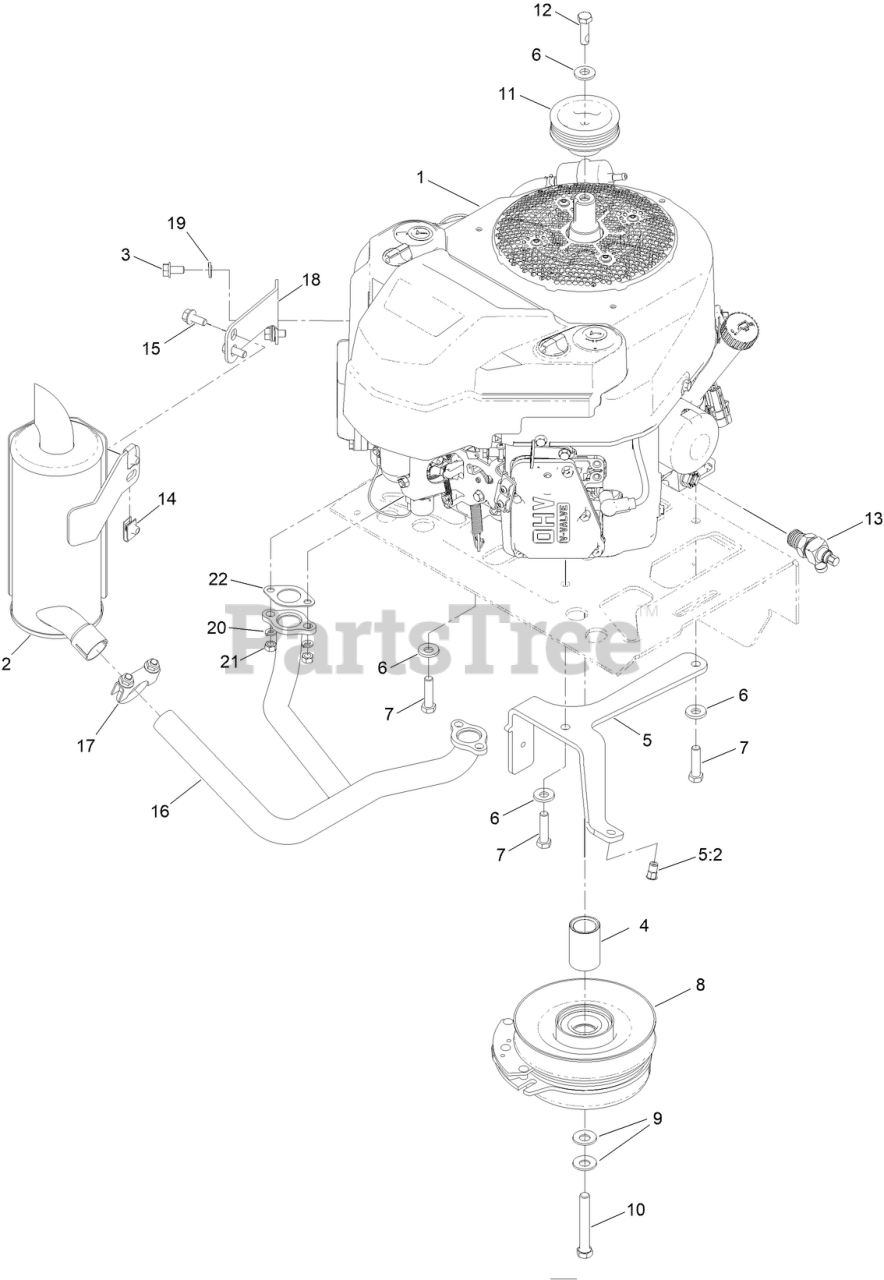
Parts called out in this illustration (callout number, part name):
1:1	KAWASAKI 49065-7007 ENGINE OIL FILTER
1:2	KAWASAKI 49019-0031 FUEL FILTER
1:4	KAWASAKI 11013-7046 FOAM PRE-FILTER
1:5	KAWASAKI 11013-0752 AIR FILTER
2	MUFFLER-VERTICAL KA
3	SCREW-HHF
4	SPACER-CLUTCH
5	ASM-CLUTCH ANCHOR W/INSERT
5:2	NUT-CLINCH,HEX
6	WASHER-BELLEVILLE
7	SCREW-HH
8	CLUTCH 105
9	WASHER-SPRING
10	SCREW-HH W/LOCTITE
11	PULLEY, CRANK
12	SCREW-HH, PATCH,
13	DRAIN-OIL VALVE
14	NUT-U
15	SCREW-HHF
16	MANIFOLD-VERTICAL KA EXH
17	Clamp-Muffler
18	BRACKET-MUFFLER VERTICAL
19	WASHER-LOCK
20	WASHER-LOCK
22	GASKET-EXHAUST
